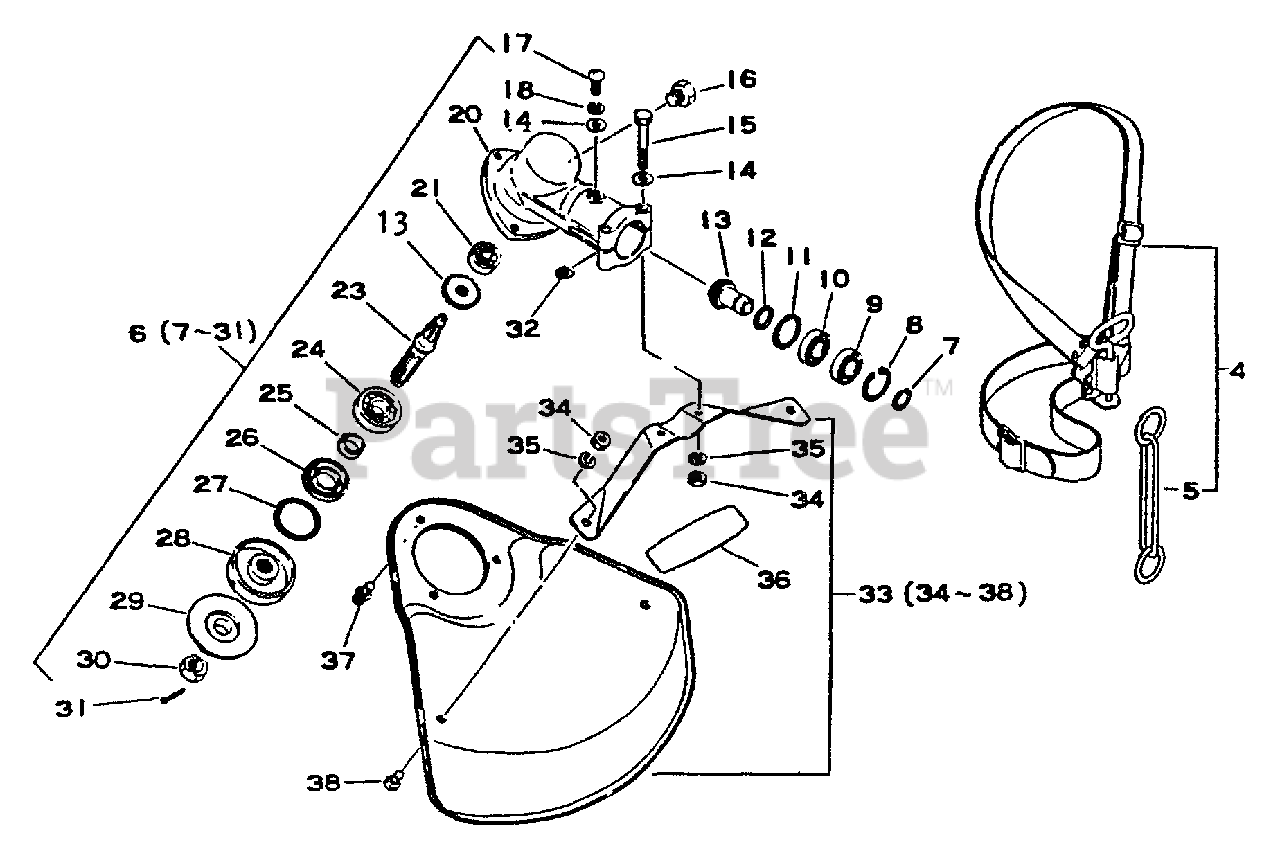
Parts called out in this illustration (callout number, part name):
4	SHOULDER STRAP ASSY
6	GEAR CASE ASSY
7	RING, RETAINING - 10
8	RING, RETAINING - 22
9	BEARING, BALL - 6900Z
10	BEARING, BALL - 6900
13	GEAR SET
14	WASHER - 5
15	BOLT - 5X35
16	BOLT - 8X8
17	SCREW - 5X10
18	LOCKWASHER - 5
20	CASE, GEAR
21	BEARING, BALL - 626
23	GEAR - SHAFT
24	BEARING, BALL - 6000
26	SEAL, OIL
27	RING, RETAINING - 26
28	ADAPTOR, BLADE - UPPER
29	ADAPTOR, BLADE - LOWER
30	NUT - 10 -- LEFT HAND
31	PIN, SPLIT - 2X22
33	SHIELD ASSY
35	LOCKWASHER - 5
36	LABEL - ECHO
37	SCREW - 5X10
38	SCREW - 5X16
